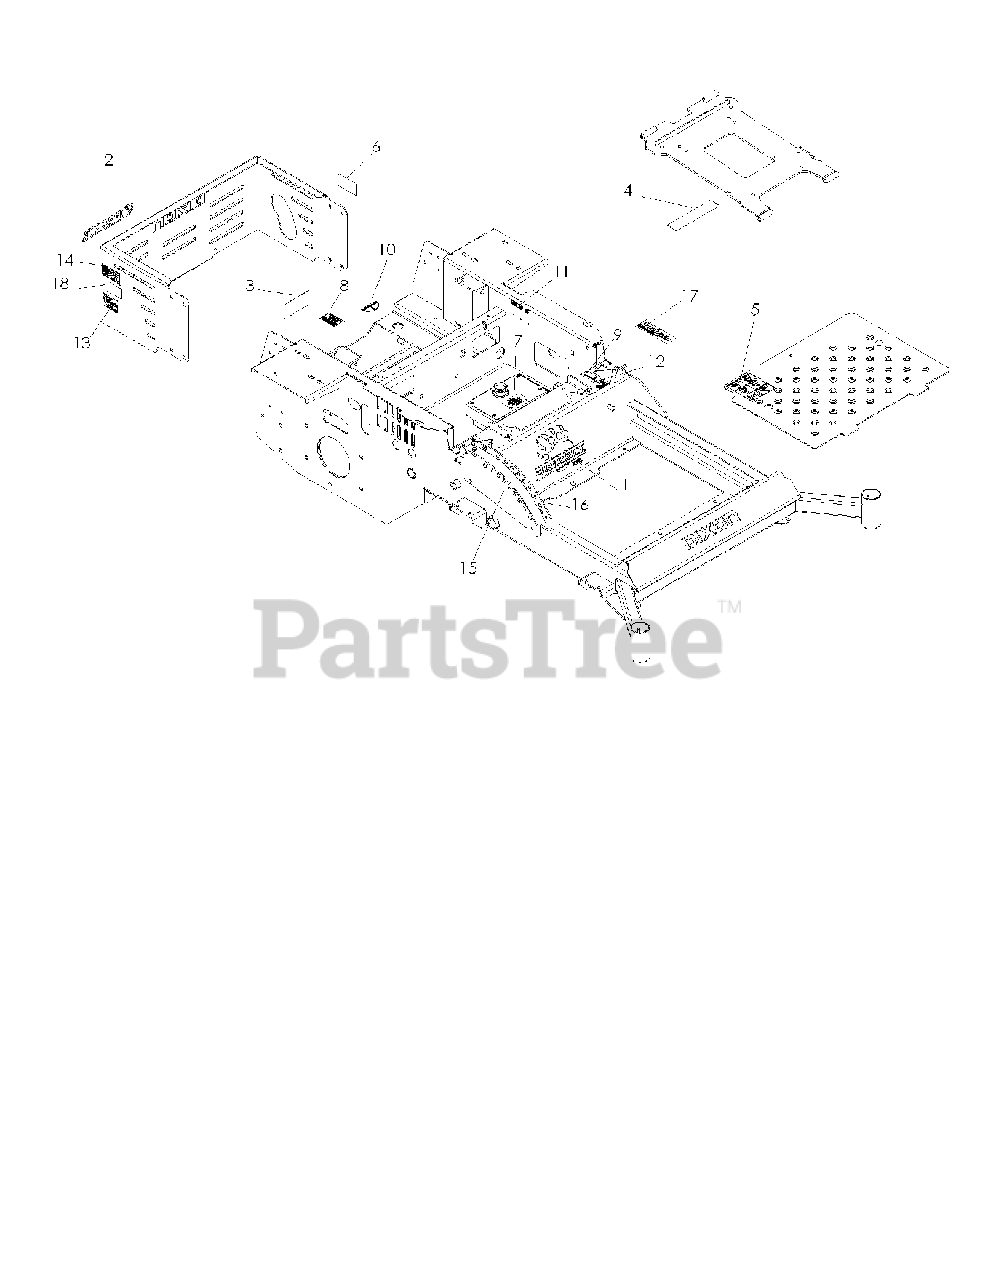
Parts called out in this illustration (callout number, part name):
1	DECAL, GRIZZLY
2	DECAL, PRO ZTR
3	DECAL, BELT DRIVE
4	DECAL, BATTERY
5	DECAL, WARNING
6	DECAL, PROP. 65
7	DECAL, OIL TANK
8	DECAL, EXHAUST
9	DECAL, MOTION CONTROL
10	DECAL, FUEL VALVE
11	DECAL, RELAYS
12	DECAL, F.S.T.
13	DECAL, PARKER
14	DECAL, FLAG
15	DECAL, HEIGHT
16	DECAL, HEIGHT
17	DECAL, FUSION
18	DECAL, KOHLER
